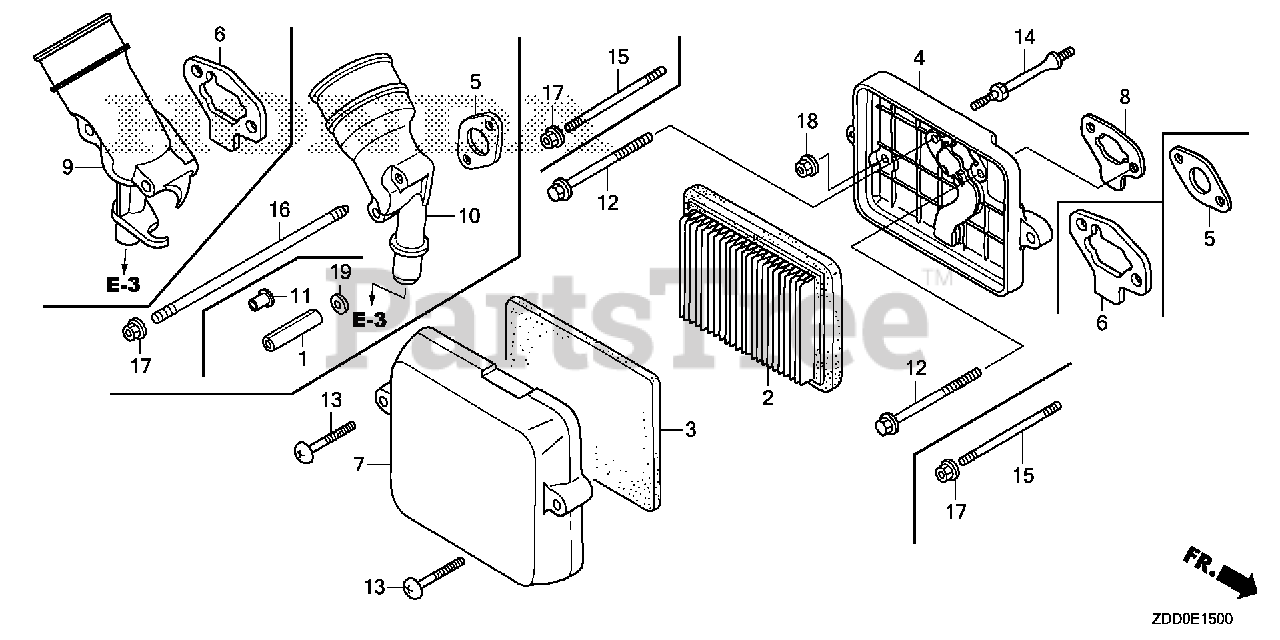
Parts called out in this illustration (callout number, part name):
2	ELEMENT, AIR CLEANER (TOYO ROKI) (ENGINE NO.)
3	FILTER (OUTER)
4	HOUSING, AIR CLEANER
7	COVER, AIR CLEANER
8	GASKET, AIR IN. JOINT
12	BOLT, FLANGE (5X77) (CT200)
13	BOLT, AIR CLEANER COVER
